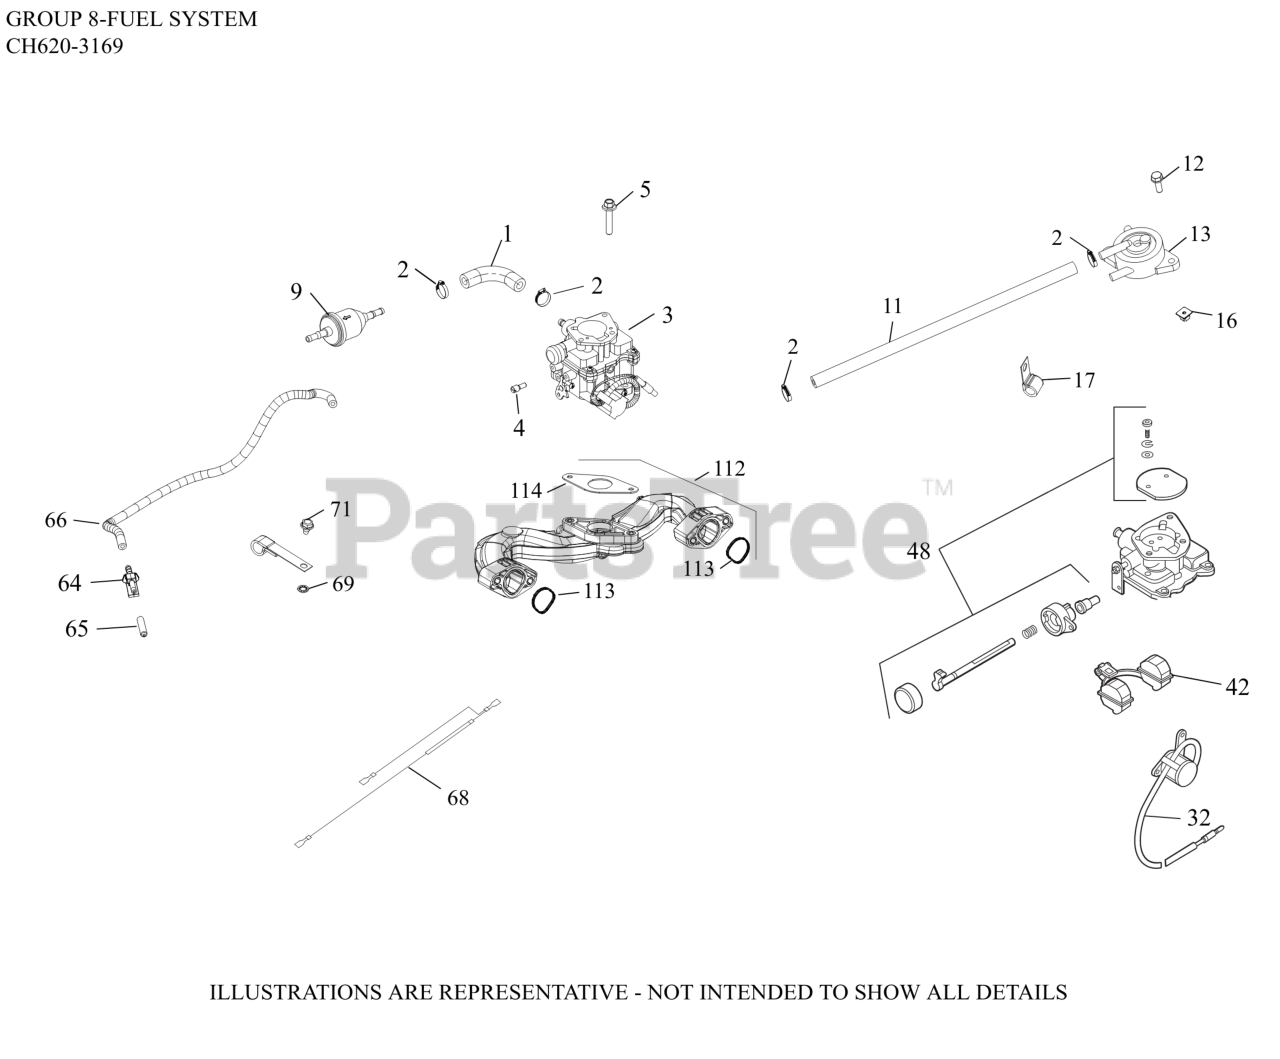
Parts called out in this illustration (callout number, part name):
1	HOSE,LW PERM.FUEL 24.00"-USE 25 111 81-S
2	CLAMP, HOSE (KM)-USE 25 237 31-S
3	KIT, CARBURETOR COMPLETE
4	SCREW, THROTTLE STOP
5	SCREW, FLG M6X1.0X25
9	FILTER, FUEL
11	LINE, FLEXIBLE FUEL 15 1/2"
12	SCREW, TAP M6X1.7X18
13	PUMP, FUEL
16	NUT, PLASTIC - BLACK
17	CLIP, CABLE (KM)
32	KIT, SOLENOID
42	KIT, REPAIR FLOAT
48	KIT, REPAIR CHOKE
64	CONNECTOR, EVAPORATIVE
65	CAP, MASKING
66	HOSE, EVAPORATIVE 20"- (#24326143S)
68	LEAD, GROUND
69	WASHER, INT TOOTH LOCK 1/4"
71	SCREW, THREAD FORMING
112	INTAKE MANIFOLD W/GASKETS
113	O-RING, INTAKE PORT
114	GASKET, CARBURETOR (PIM, CH)
NI	KIT, HIGH ALT (4000-8000 FT)
NI	KIT, HIGH ALT (8,000+ FT)
NI	KIT, REPAIR CARBURETOR
